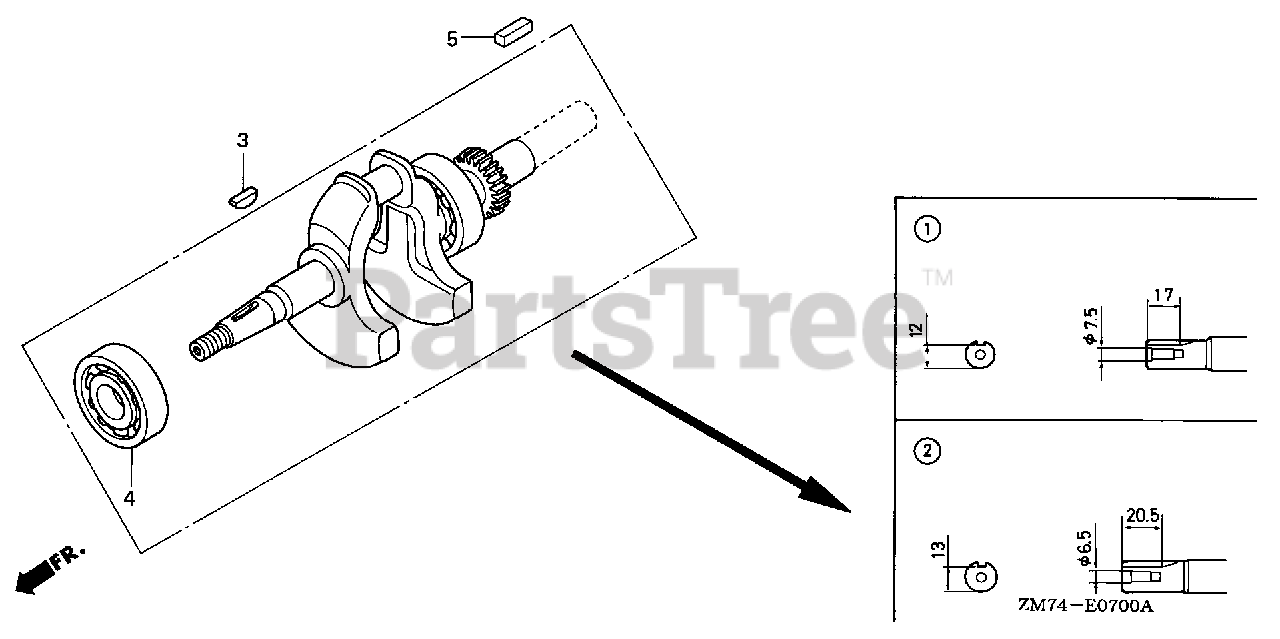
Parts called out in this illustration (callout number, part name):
1	CRANKSHAFT
3	KEY, SPECIAL
4	BEARING, RADIAL BALL (6203)
5	KEY (5MM)
